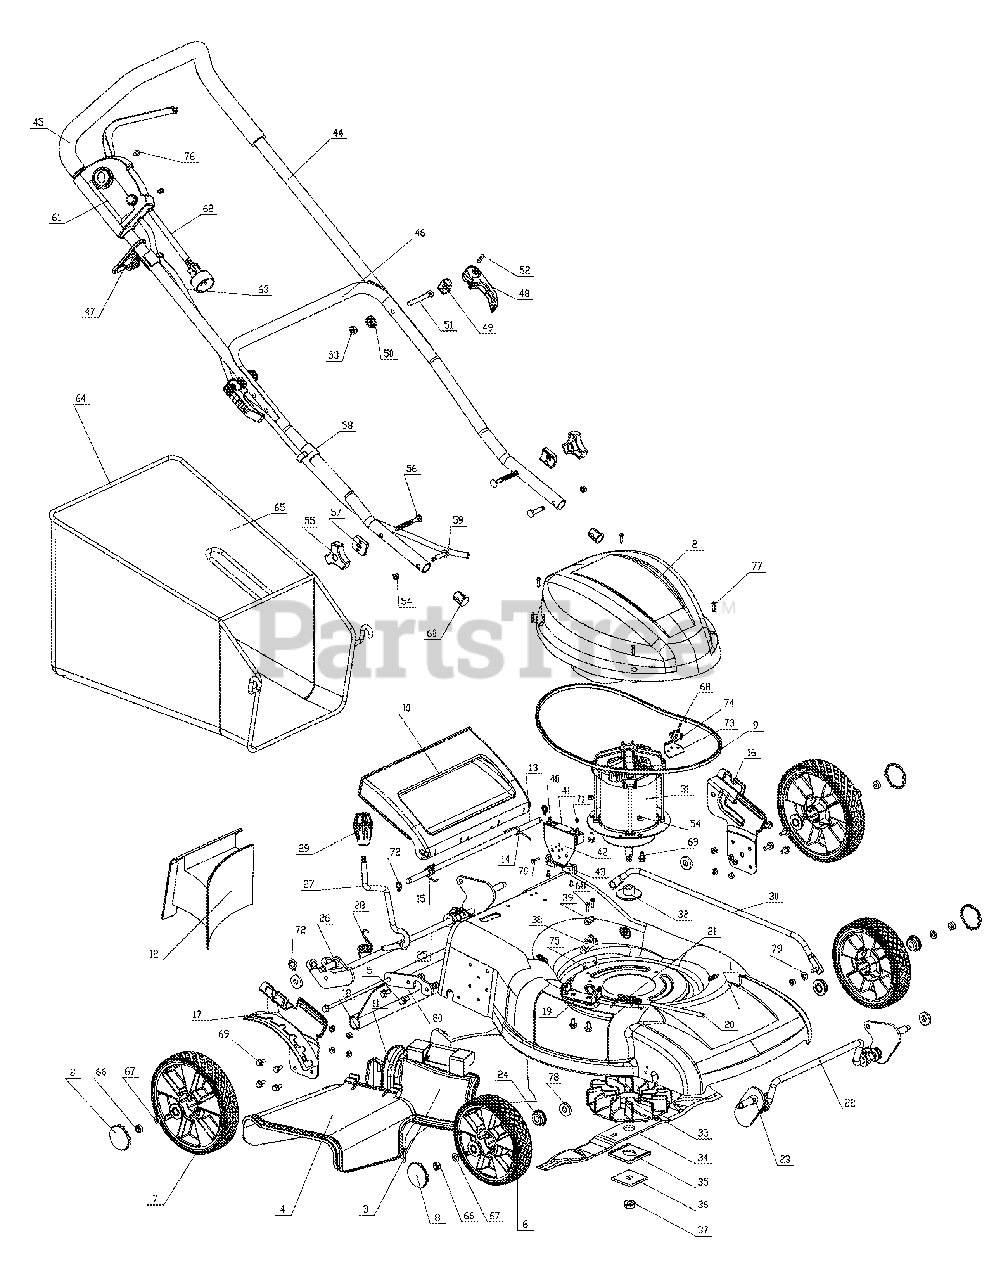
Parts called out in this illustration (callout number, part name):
2	Shroud
3	Mulch Door
4	Discharge Chute
5	Trail Shield
6	Front Wheel
7	Rear Wheel
8	Wheel Cap
9	Shroud Seal
10	Rear Door
11	Rear Baffle
12	Mulch Plug
14	Spring
15	Spring
16	Left Bracket
17	Right Bracket
18	Trailshield Rod
19	Mulch Door Bracket
20	Mulch Door Rod
21	Mulch Door Spring
22	Front Shaft Assembly
23	Spacer Bushing
24	Wheel Bushing
25	Rear Shaft Assembly
26	Spacer Bushing
27	Height Adjust Handle
28	Height Adjust Spring
29	Height Adjust Knob
30	Height Adjust Rod
31	Motor
32	Flange
33	Electric Motor Fan
34	Blade
35	Washer
36	Washer
38	Strain Relief Bracket
39	Strain Relief Cap
40	Resistor
41	Resistor Holder
42	Resistor Bracket
43	Resistor Base
44	Upper Handle
45	Handle Grip
46	Lower Handle
47	Cord Retainer
48	Quick Release Handle
49	Washer
50	Quick Release Knob
51	Quick Release Pin
54	Nut, M6
55	Wing Knob
56	Screw, M8
57	Washer
58	Cord Clip
59	Shoulder Bolt
61	Switch Box Assembly
62	AC Power Cord
63	Motor Cord
64	Grassbag Frame
65	Grassbag
66	Nut, M8
67	Washer
68	Screw, St, M4.2 x 16
69	Screw, M6x12
70	Screw, M4x16
71	Nut, Lock, M4
72	Ring, Snap
73	Base, Electric-Bridge
74	Electric, Bridge
75	Screw, St, M4.8 x 16
76	Screw, St, M4.2 x 25
77	Screw, M5x12
78	Washer, Spring
79	Pin, Cotter
80	Bracket, Wheel
